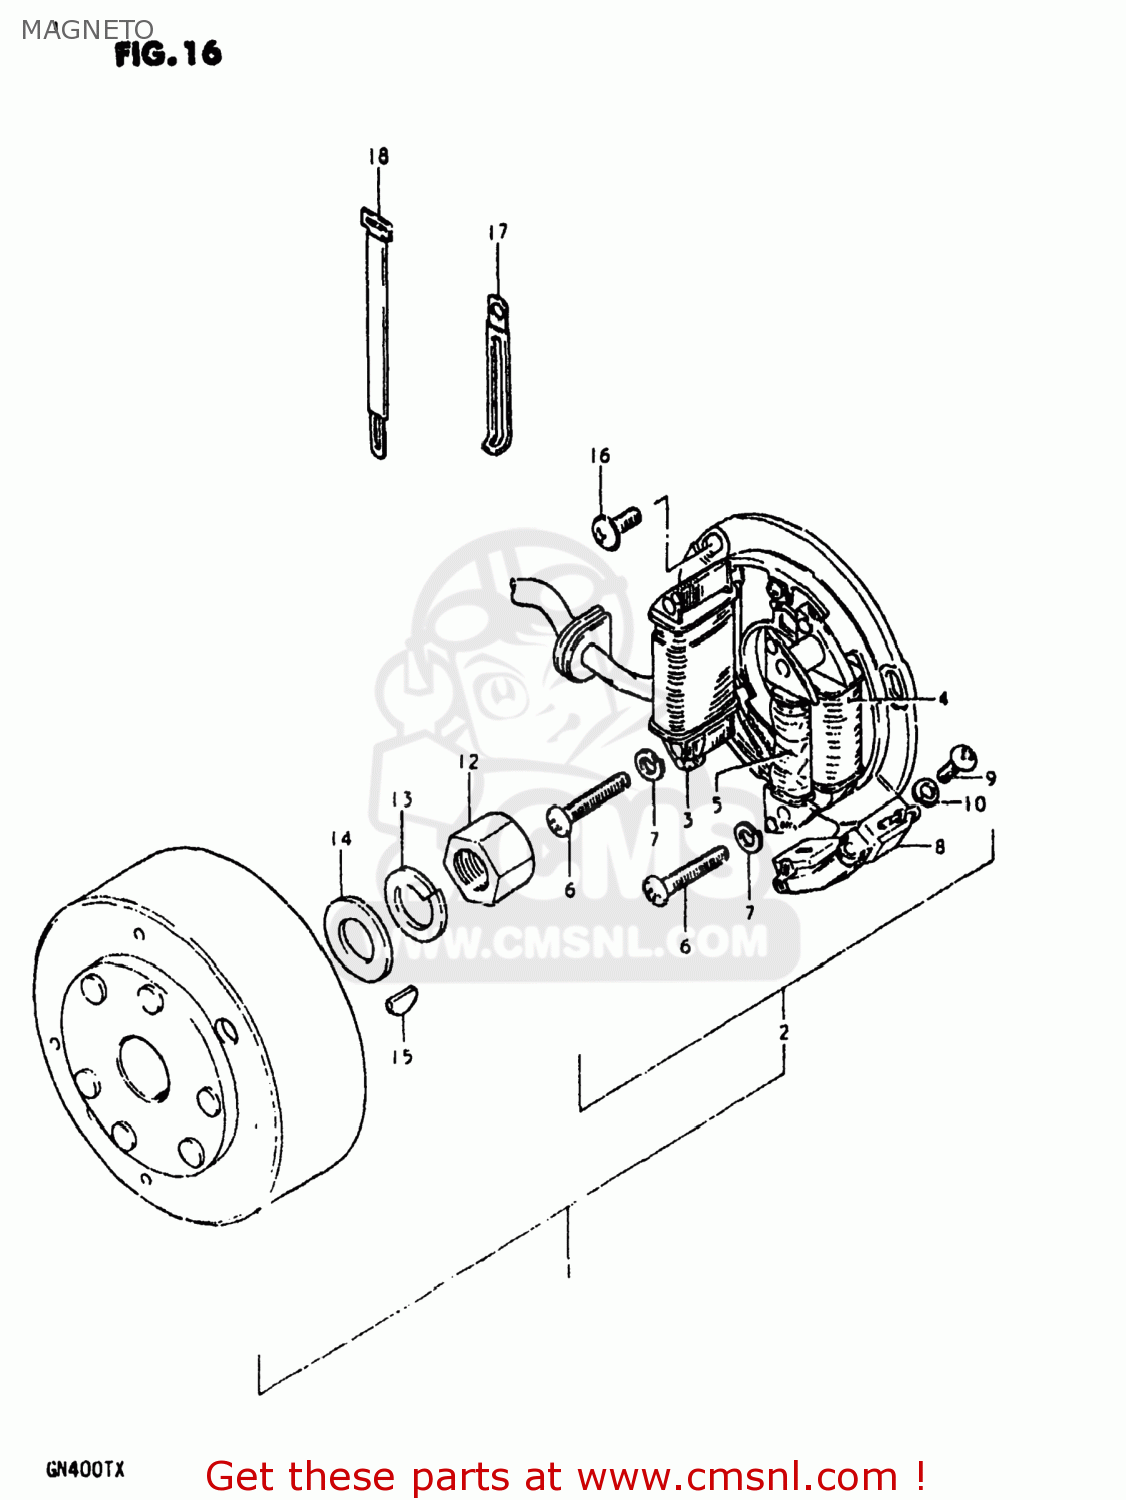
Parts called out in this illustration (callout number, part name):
1	MAGNETO ASSEMBLY
2	STARTER ASSY
3	COIL,LIGHTING
4	COIL,PRIMARY
5	COIL,PULSER
6	SCREW
7	LOCK WASHER
8	COIL,PULSER
9	SCREW
10	LOCK WASHER
11	ROTOR,FLYWHEEL
12	NUT
13	LOCK WASHER
14	WASHER(14X27X3)
15	KEY 4MM
16	SCREW(5X14)
17	CLAMP
18	CLAMP L:110
